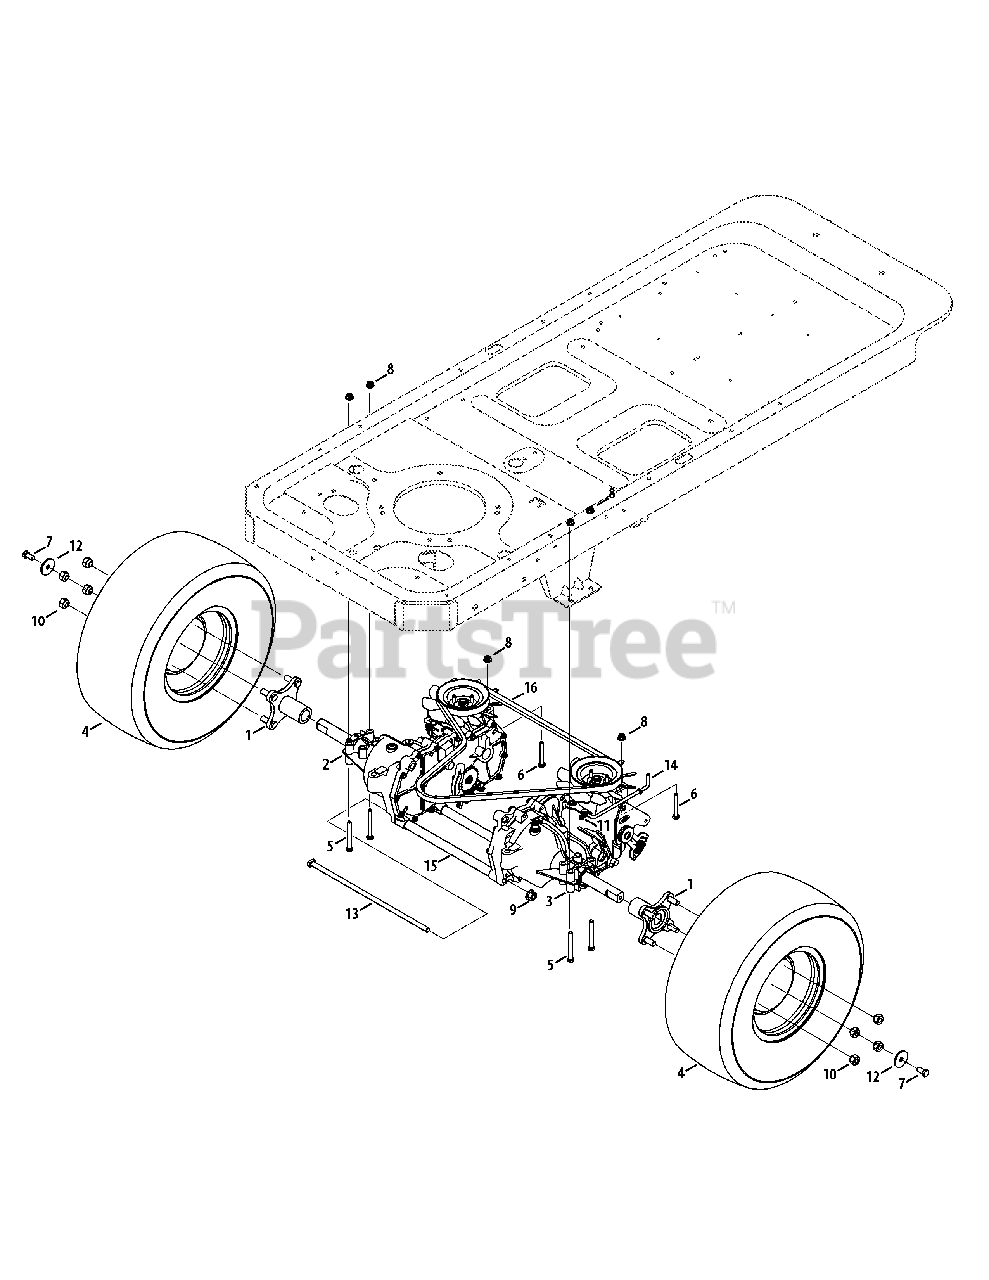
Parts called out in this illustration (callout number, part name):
1	Wheel Hub, 7/16-14 x 1.6
2	Transmission Assembly, LH
3	Transmission Assembly, RH
5	Hex Cap Screw,5/16-18 x 2.75
6	Hex Cap Screw,5/16-18 x 2.25
7	Hex Cap Screw, 3/8-16 x .75
8	Hex Flange Nut,5/16-18
9	Hex Flange Nut, 7/16-20
10	Lug Nut, 7/16-14
11	Bow-Tie Cotter Pin
12	Flat Washer, .39 x 1.5
13	Rod, .405 x 14
14	Bypass Rod
15	Tube, .45 x .69 x 10.2
